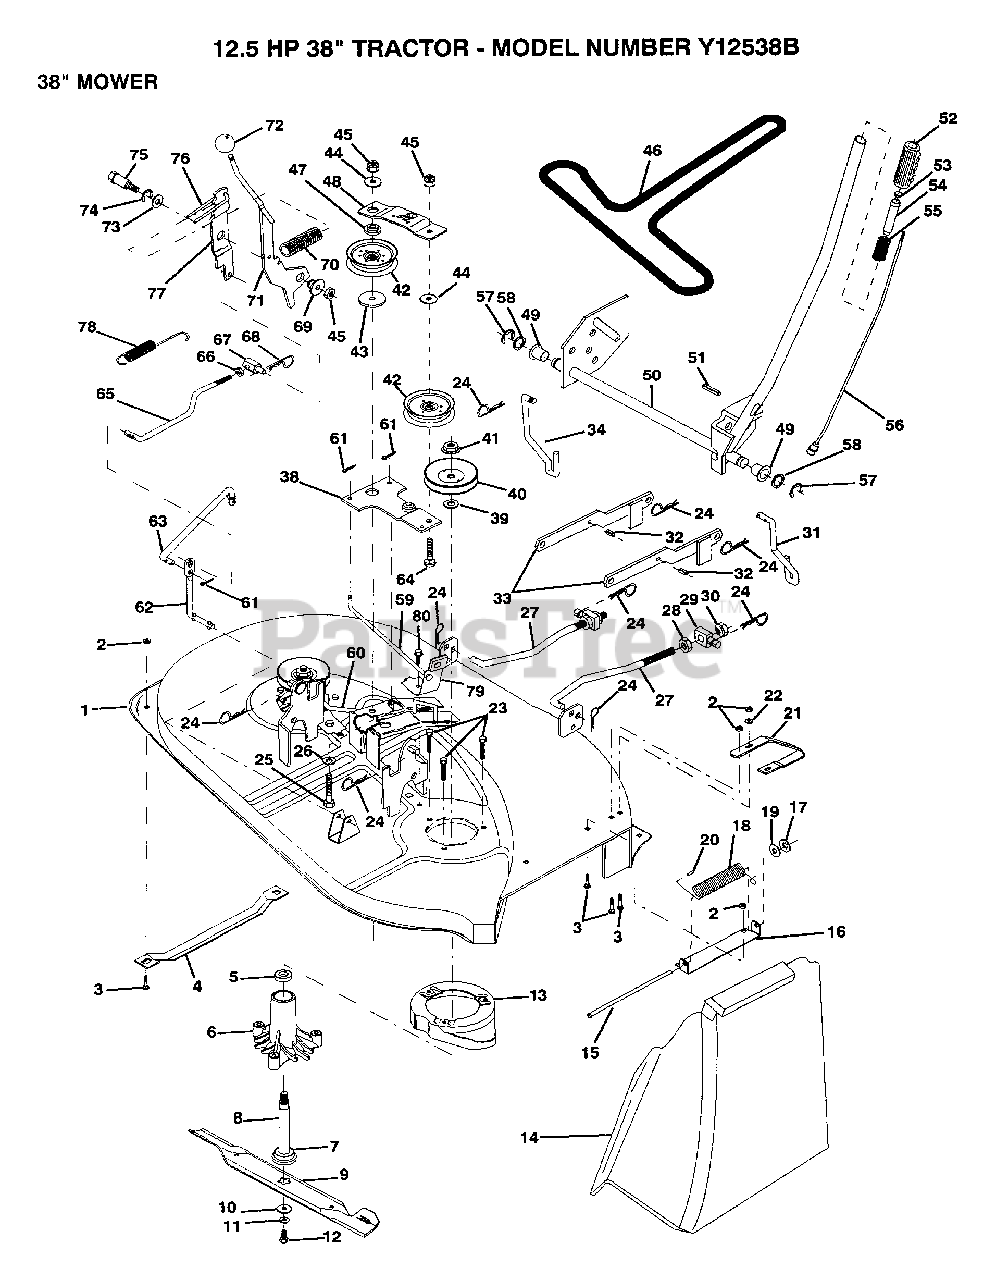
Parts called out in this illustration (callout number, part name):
3	BOLT
4	RUNNER-LH M
5	BEARING
6	HSG ASM MANDREL
7	BEARING.BALL
10	WASHER BLADE
12	BLADE BOLT
14	DEFLECTOR-SHLD T
15	ROD-HINGE T
17	NUT PUSH M
19	WASHER
20	CAP-SLEEVE LT
21	RUNNER RH
22	WASHER M
25	BOLT
26	WASHER GT
27	LINK.FRONT
28	NUT
29	TRUNION
30	NUT.LK.W/WSH.1/2.
31	LIFT LINK RH
32	SPRING PIN
33	SUSP ARM REAR
34	LINK LIFT LH
38	IDLER ARM ASSY
39	WASHER
42	FLAT IDLER PULLEY
43	SPACER RETAINER
44	WASHER GT
46	BELT-V.88.12.MW
47	RETAINER SPACER
48	IDLER ARM STIFF
49	NYLON BEARING
51	PIN-GROOVE LT
52	GRIP
58	WASHER
59	BRAKE ROD RH
60	BRAKE ROD LH
62	PIVOT ROD
63	CLUTCH ROD SECOND
64	BOLT
66	NUT
67	TRUNION
68	RETAINER M
69	BUSHING
71	CLUTCH ARM PRI AS
72	KNOB T (1/2-HOLE)
73	WASHER
74	RING
75	SHOULDER BOLT
76	SPRING KEEPER
77	CLUTCH ARM SECOND
78	RETURN SPRING
79	BRAKE ASM
80	SCREW
